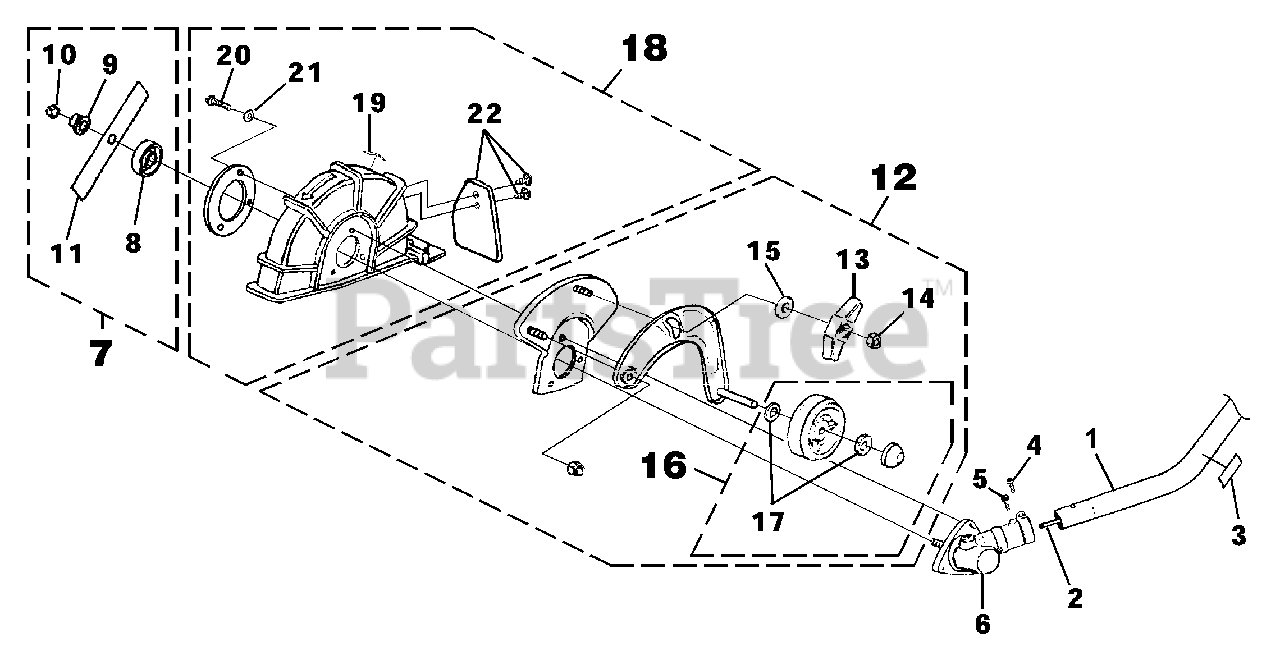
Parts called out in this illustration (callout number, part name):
1	DRIVESHAFT HOUSING
2	SHAFT-Flexible
3	DECAL-Warning
4	SCREW-Cap Socket Hd. (1/4-20 X 7/8")
5	SCREW-Sems Hex Hd. (10-24 X 1/2")
6	GEAR HEAD
7	BLADE KIT
8	WASHER-Flanged
9	WASHER-Flanged (Lower)
10	NUT-Lock
11	BLADE (2" X 9") (Qty.-2)
12	SUPPORT ARM ASSEMBLY
13	KNOB-Adjusting
15	WASHER-Flat
16	WHEEL KIT
17	WASHER-Flat
18	GUARD KIT
19	DECAL-Warning
20	SCREW-Hex Hd. (10-24 X 5/8")
21	WASHER-Lock (#10)
22	FLAP KIT
